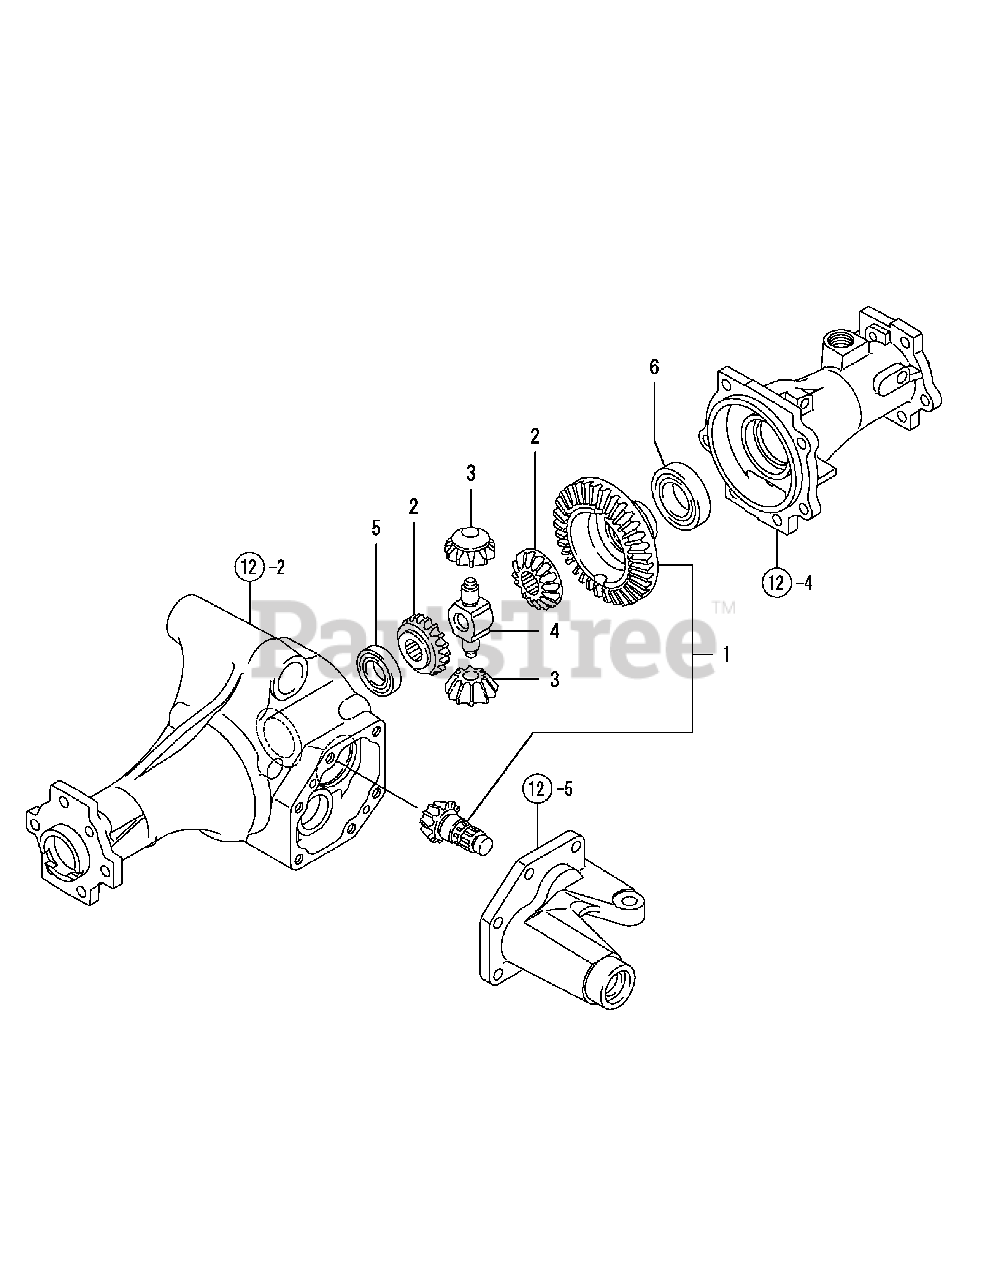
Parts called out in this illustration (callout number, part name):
1	Pinion, Drive Kit
2	Gear,Diff.Side
3	Gear,Diff Pinion
4	Shaft,Diff.Pinion
5	Ball Bearing 6005
